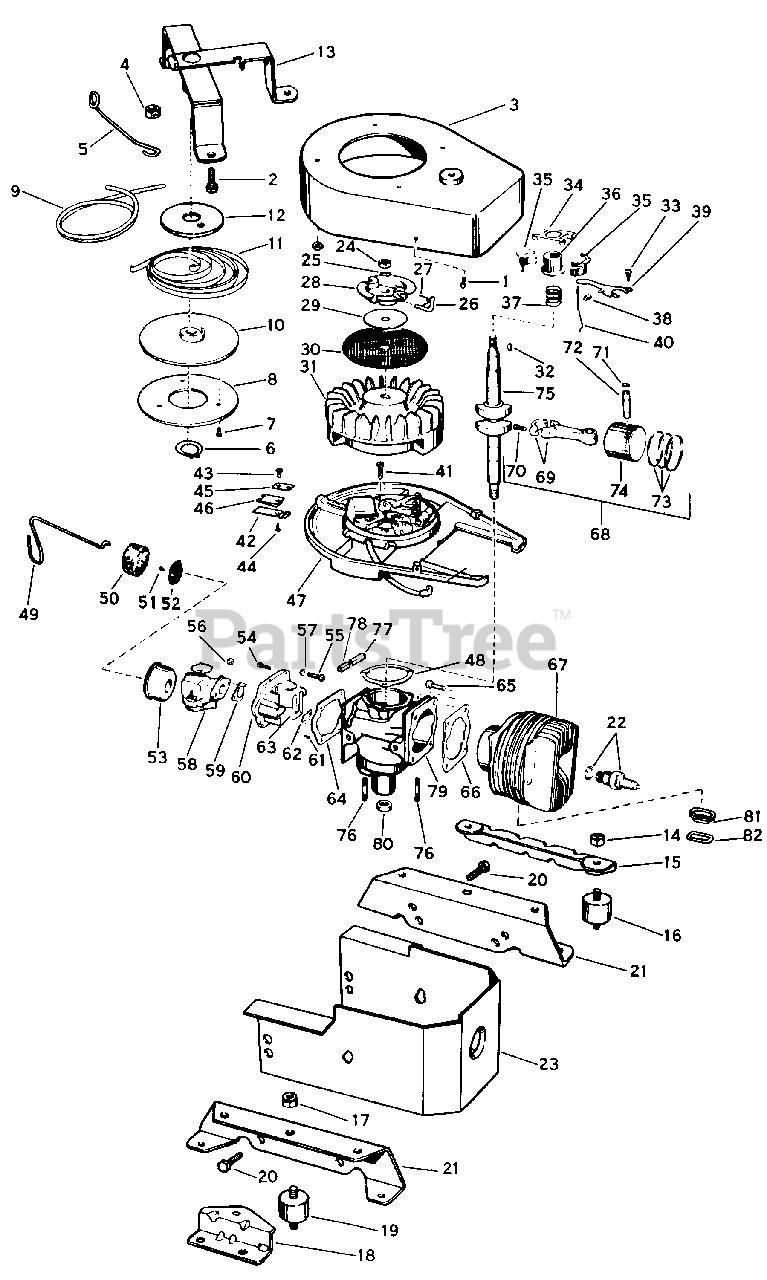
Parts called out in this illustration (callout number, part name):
1	Screw-Shroud to Arm. Plate
2	Screw-Starter to Shroud
4	Nut-Guide Attaching
5	Guide-Starter Rope
6	Ring-Grip (Starter Brg. Pin)
7	Screw-Thread Cutting
8	Plate-Pulley
9	Rope-Starter
10	Pulley-Rewind
11	Spring-Recoil
12	Washer-Starter Spring Ret.
13	Starter Brkt. and Pin Assy.
14	Nut-Nylok (Rubber Mount, Left)
15	Bracket-Shock Mounting, Housing, Left
16	Mount-Rubber, Left
17	Nut-Nylok (Rubber Mount, Right)
18	Bracket-Shock Mounting, Housing, Right
19	Mount-Rubber, Right
20	Screw-Engine Mounting Bracket Assembly
21	Bracket-Shock Mtg., Engine
22	Spark Plug and Gasket
23	Shield-Cylinder and Crankcase
24	Nut-Flywheel
25	Lockwasher-Flywheel
26	Pin-Starter
27	Spring-Starter Pin
28	Pulley-Flywheel
29	Washer-Flywheel
30	Screen-Flywheel
31	Flywheel Assembly
32	Key-Crankshaft
33	Screw-Governor
34	Yoke-Governor
35	Weight-Governor
36	Collar-Governor
37	Spring-Governor
38	Block-Wear, Governor
39	Governor Lever and Wear Block Assembly
40	Rod-Governor
41	Screw-Crankcase to Arm. Plate
42	Contact and Sleeve Assembly-Shut-off
43	Sleeve-Nylon
44	Screw-Shut-Off Switch
45	Insulator-Contact
46	Cover-Shut-Off Switch Contact
47	Armature Plate Assy.-Complete
48	Gasket-Crankcase to Arm. Plate, .005"
48	Gasket-Crankcase to Arm. Plate, .010"
49	Clip-Air Filter
50	Element-Air Filter
51	Screw-Air Filter
52	Screen-Air Filter
53	Cup-Air Filter
54	Screw-Reed Plate to Crankcase
55	Screw-Reed Plate to Carburetor
56	Nut-Reed Plate to Carb. Screw
57	Washer-Reed Plate to Carb. Screw
58	Carburetor Assembly
59	Gasket-Carburetor
60	Reed Plate Assembly
61	Screw-Reed to Reed Plate
62	Plate-Back-up. Reed
64	Gasket-Reed Plate to Crankcase
65	Screw-Cyl. to Crankcase
66	Gasket-Cyl. to Crankcase
67	Cylinder and Sleeve Assembly
68	Piston and Connecting Rod Assy.
69	Connecting Rod
70	Screw-Connecting Rod
71	Ring-Spring
72	Pin-Wrist
73	Ring-Piston
75	Crankshaft
76	Stud-Crankcase to Muffler
77	Shield-Dust, Crankcase, Right
78	Shield-Dust, Crankcase, Left
79	Crankcase Brg. and Oil Seal Assy.
80	Oil Seal
81	Sleeve-Muffler Gasket
82	Gasket-Exhaust
